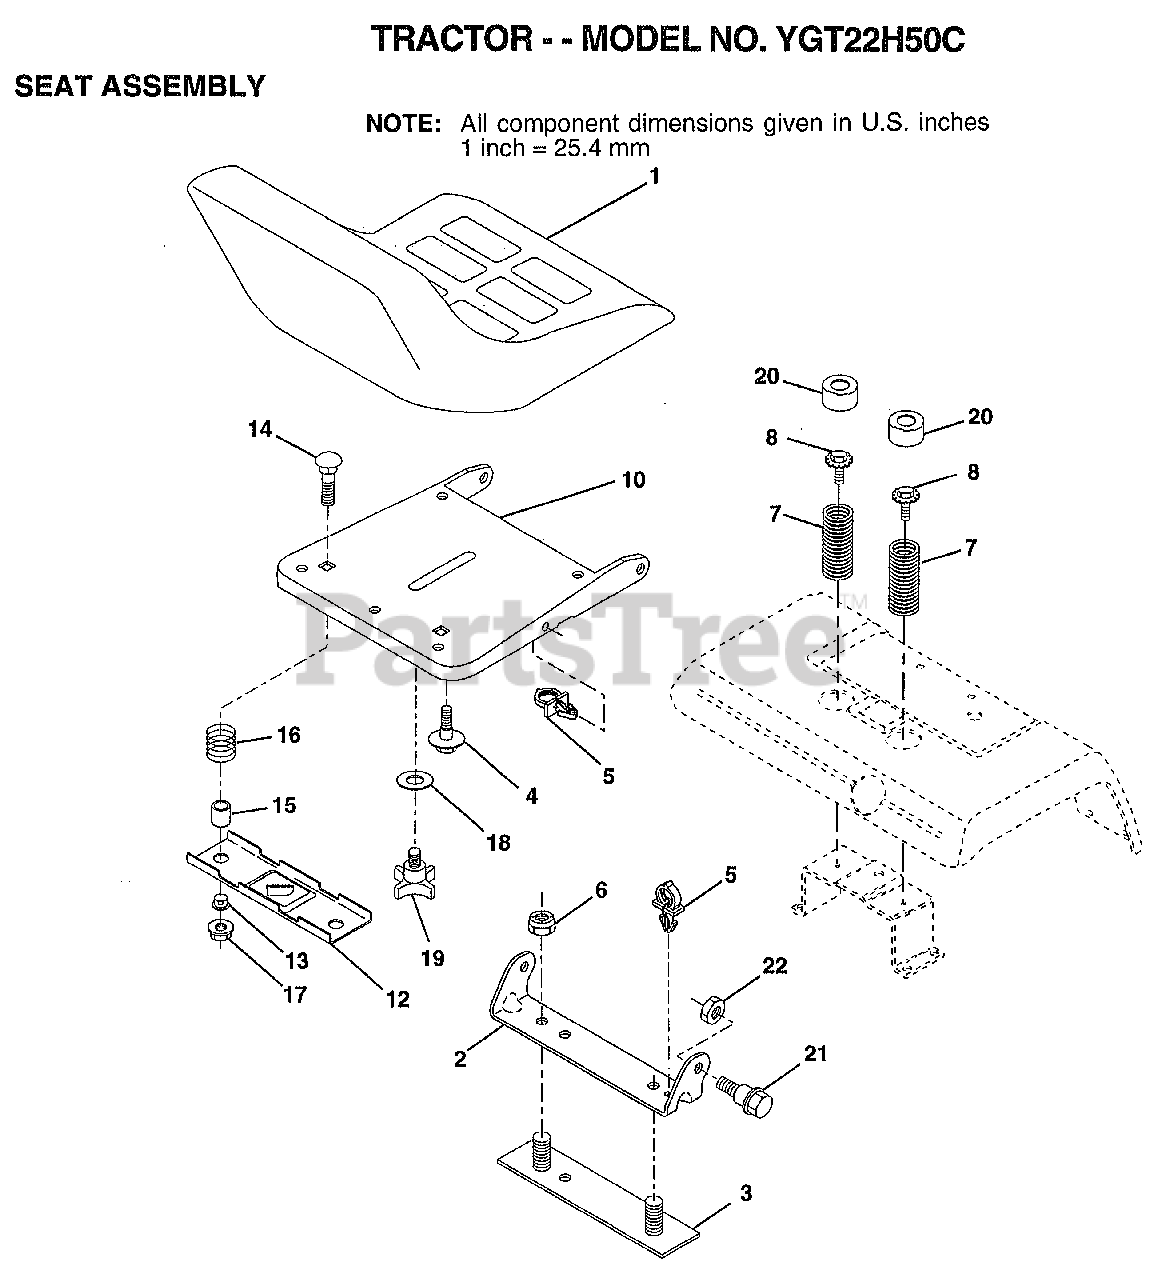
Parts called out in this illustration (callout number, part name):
2	BRACKET PVT SEAT
3	STRAP ASM FENDER
4	"BOLT,SHOULDER"
5	CLIP.PUSH-IN.HING
7	SPRING COMPRESSIO
8	BOLT.5/16-18.UNC
10	PAN-SEAT
12	BRKT SWITCH
13	BUSHING
14	BOLT-RD HD SQ NK
15	SPACER SPLIT
16	SPRING COMPRESSED
18	WASHER
19	"KNOB 1/2"" YT"
20	CAP SPRING
21	"BOLT,SHOULDER"
